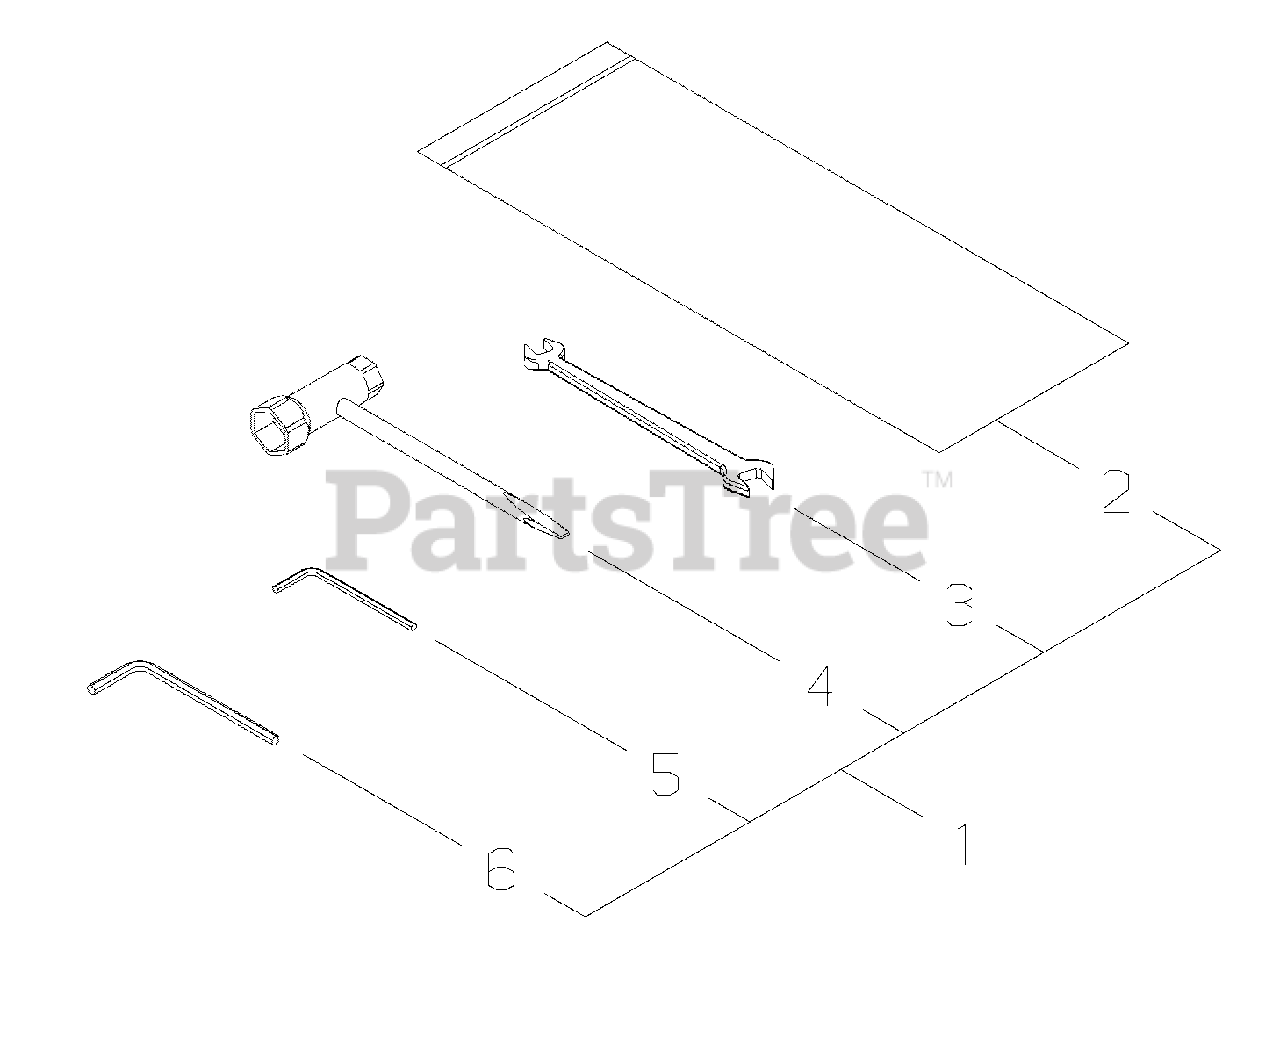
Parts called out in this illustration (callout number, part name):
1	TOOL KIT
2	BAG, TOOL
3	SPANNER - 8X10mm
4	T-WRENCH - 13X16mm
5	HEX KEY - 3mm
6	HEX KEY - 4mm
